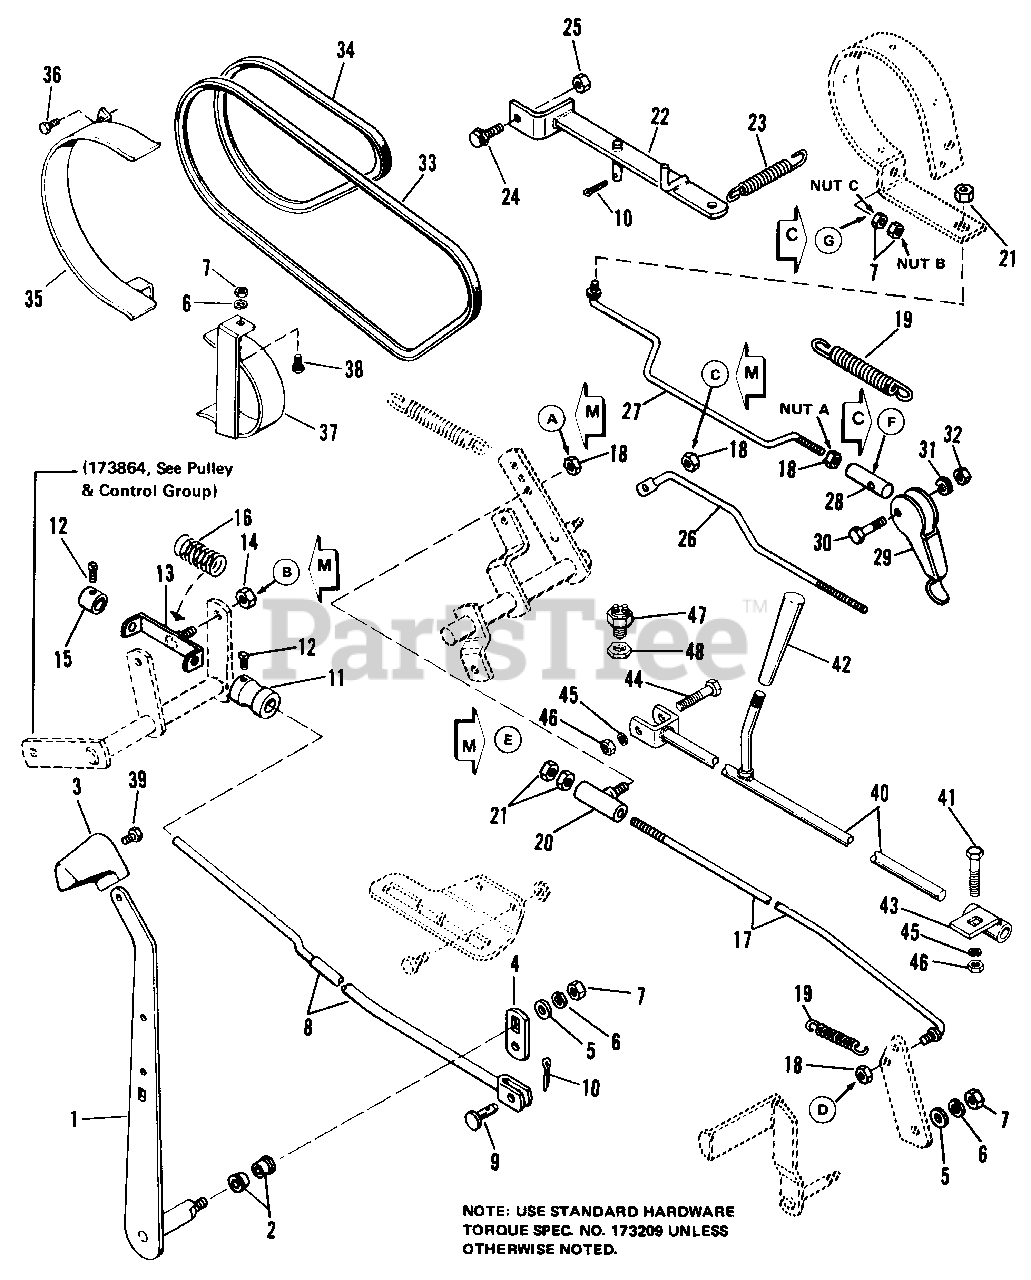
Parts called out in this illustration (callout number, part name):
1	LEVER ASSY
5	WASHER, 3/8
6	LOCKWASHER, 3/8
7	NUT, Hex, Full, 3/8-16
10	PIN, Cotter, 3/32 x 3/4
11	DETENT, Brake
12	SETSCREW, 1/4-20 x 3/8
13	GUIDE ASSY, Rod
14	NUT, Hex, Lock, 3/8-24
15	COLLAR, Set
17	ROD ASSY, Brake & Control
18	NUT, Hex, Lock, 5/16-18
20	GUIDE ASSY, Rod
21	NUT, Hex, Full, 5/16-18
22	LEVER ASSY, Brake
24	PAD ASSY, Brake
25	NUT, Hex, Jam, 5/16-18
26	ROD, Brake
27	ROD ASSY, Parking Brake
29	LEVER, Parking Brake
30	CAPSCREW, Hex Hd., 1/4-20 x 1-1/4
31	LOCKWASHER, Dbl., 1/4
32	NUT, Hex, Lock, 1/4-20
35	GUARD ASSY, Pulley
36	SCREW, Taptite 5/16-16 x 5/8
37	GUARD ASSY, Belt
38	BOLT, Carriage, 3/8-16 x 3/4
39	SCREW. Thd. Forming, 1/4-20 x 7/8
40	ROD ASSY, Shift
41	CAPSCREW, Hex Hd., 5/16-18 x 1-1/2
42	HANDLE, Shift Rod
43	GUIDE ASSY, Shift Assy
44	CAPSCREW, Hex Hd., 1/4-20 x 3/4
45	LOCKWASHER, 5/16
46	NUT, Hex, Lock, 5/16-18
47	SWITCH, Interlock
48	NUT, Pal
